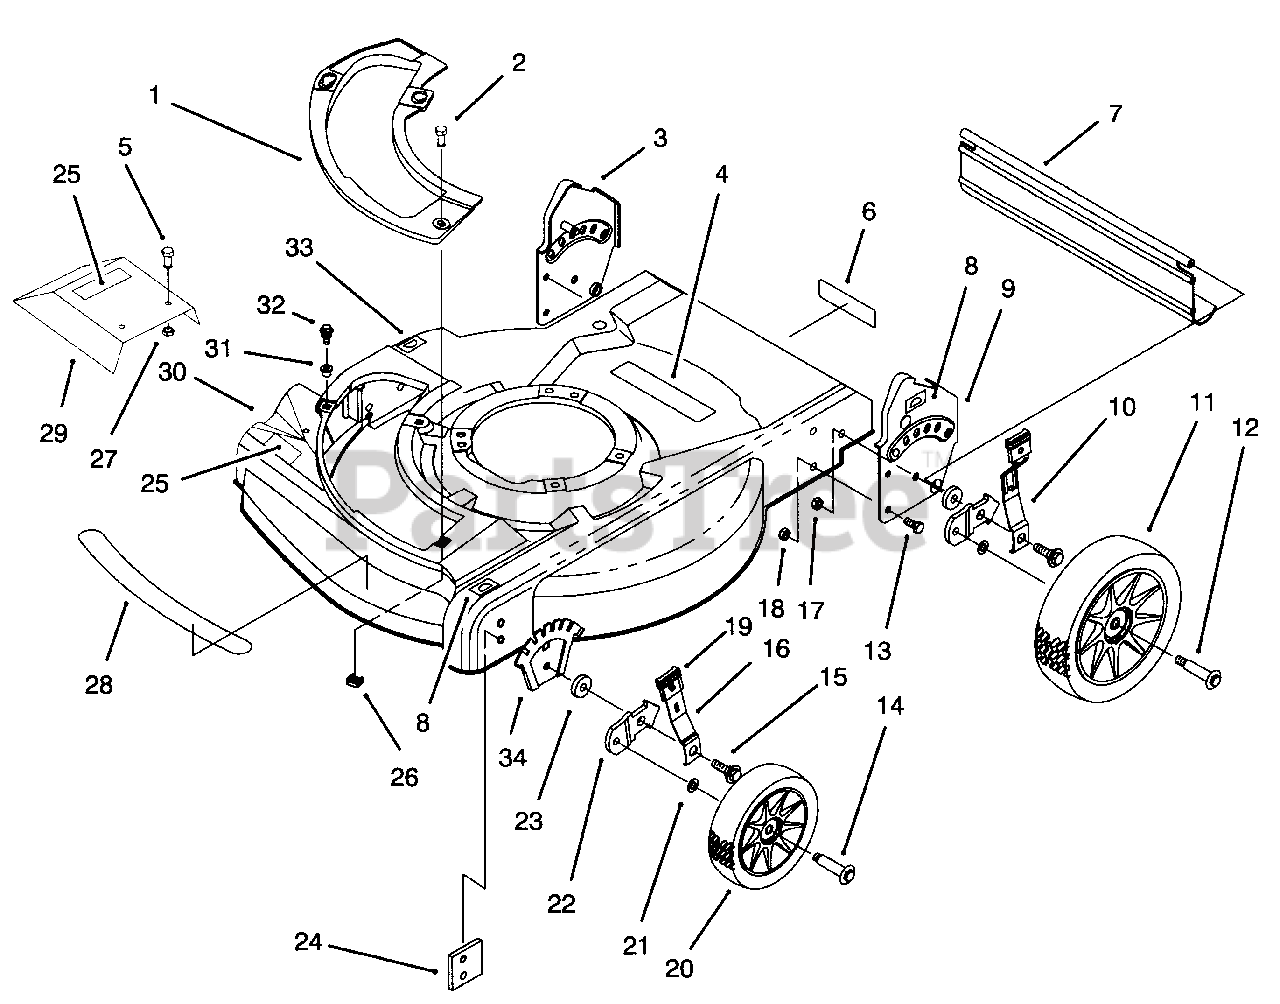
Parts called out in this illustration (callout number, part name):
1	Plate-Cover
3	Handle Brkt. Ass'y-R.H.
4	Decal-Danger
6	Decal-Noise
7	Shield-Trailing
8	Decal-H.O.C. L.H.
9	Handle Brkt. Ass'y-L.H.
10	Spring Arm Ass'y
11	Wheel & Tire Assembly
12	Bolt-Shoulder
13	Screw-Hex Hd. Cap
14	Bolt-Shoulder
15	Bolt-Shoulder Height Adj.
16	Spring Arm Ass'y
17	Nut-Lock
18	Nut-Lock
19	Knob-Height Adjust
20	Wheel & Tire Assembly
22	Bracket-Wheel Height Adj.
24	Plate-Baffle
25	Decal-Warning
26	Nut-Cage
27	Nut-Lock
28	Decal-Deck 345VP
29	Guard-Plate
31	Grommet-Plastic
32	Screw-Sems Thr'd Form
33	Decal-H.O.C. R.H.
34	Plate-Height Adjust
